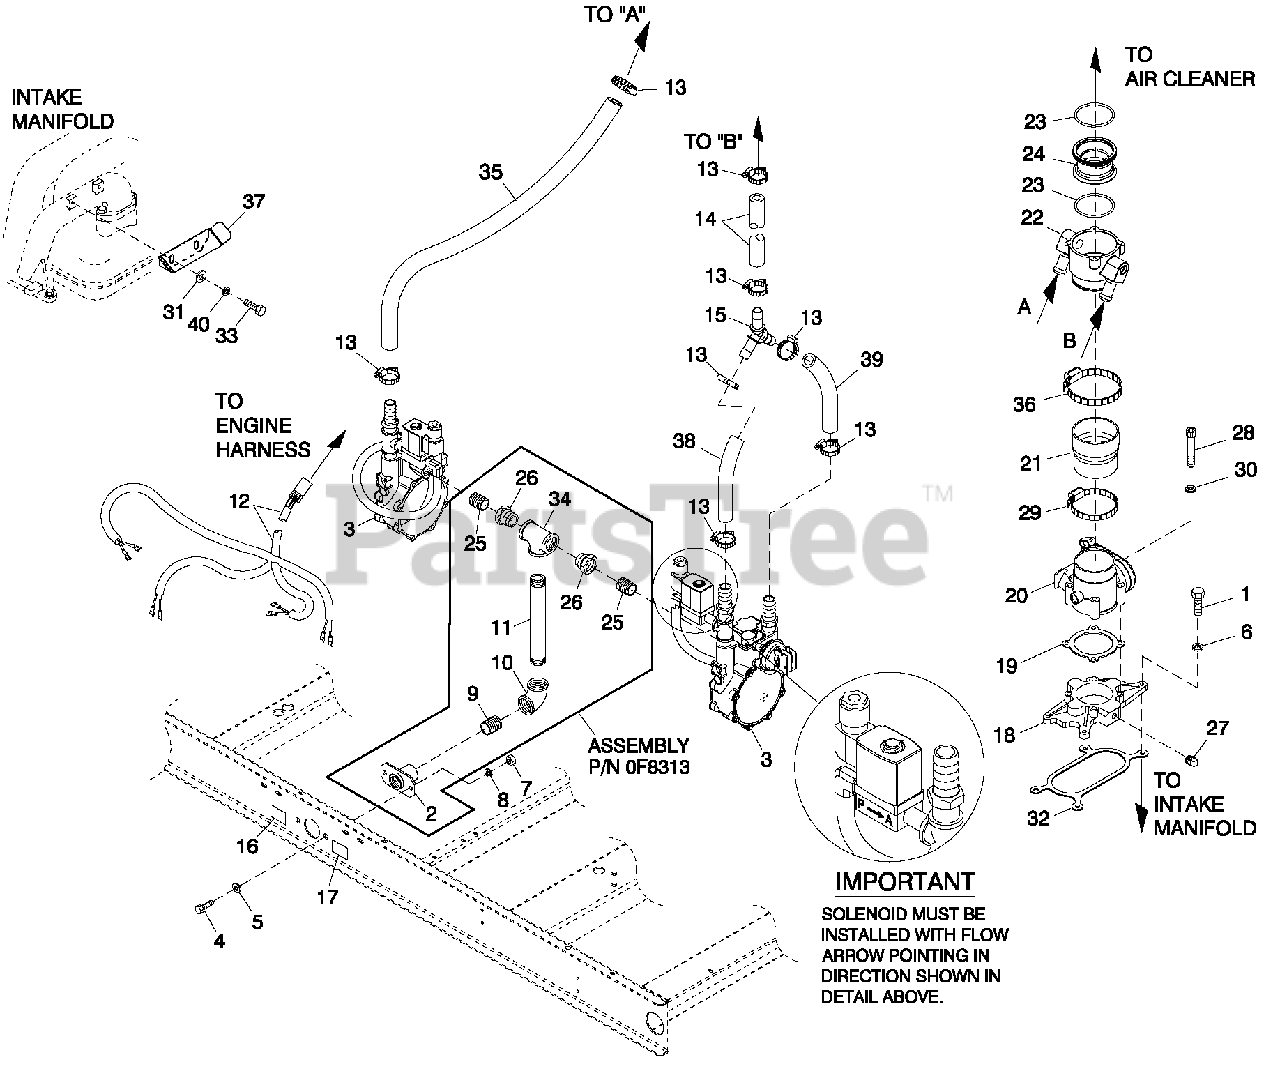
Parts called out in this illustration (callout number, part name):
1	SCREW HHC 5/16-18 X 1-1/4 G5
2	SUPPORT NAT GAS SOLENOID
3	REG ASSY 5.4L 80 KW NG CPL
4	SCREW HHC #12-1.75 X 20 G8.8
5	WASHER FLAT 1/2 ZINC
6	WASHER LOC K M8-5/16
7	NUT HEX M12-1.75 G8 YEL CHR
8	WASHER LOC K1/2
9	NIPPLE CLOSE 1.25 NPT X 1.625
10	ELBOW 90D1-1/4 NPT
11	NIPPLE PIPE 1-1/4 NPT X 3 (100 KW)
12	HARNESS, FUEL JUMPER DUAL REG (100 KW)
13	CLAMP HOSE #8.53-1.00
14	HOSE 3/4 ID SAE-30R2 (42" LG)
15	Y CONNECTOR 500 SERIES BARBS
16	DECAL INLET PRESSURE
17	DECAL FUEL INLET NG
18	ASSY,ADAPTER,THROTTLE BODY
19	GAS KET GOVERNOR ACTUATOR
20	ACTUATOR BOSCH 60 GOVERNOR
21	REDUCER 3.0" TO 2.75" TURBO
22	MIXER 40/60MM ACTUATOR ASSY
23	O-RING 2-3/4X3/32X2-15/16
24	VENTURI, THROTTLE 42MM (100 KW)
25	NIPPLE CLOSE 3/4X1.375
26	BSHGRDCR HEX1-1/4-3/4
27	PLUG STD PIPE 1/4 STEEL SQ HD
28	SCREW SHC M6-1.0X 50 C8.8
29	CLAMP HOSE #44 2.31-3.25
30	WASHER LOC K M6-1/4
31	WASHER FLAT M6
32	GAS KET ADAPTER THROT BODY
33	SCREW HHC M6-1.0X 20 G8.8
34	PIPE TEE 1-1/4 NPT
35	HOSE 3/4 ID SAE-30R2 (45" LG)
36	CLAMP HOSE #52 2.81-3.75
37	BRACKET, HOSE RISER
38	HOSE 3/4 ID SAE-30R2 (9.5" LG)
39	HOSE 3/4 ID SAE-30R2 (12" LG)
40	WASHER LOC K M6-1/4
